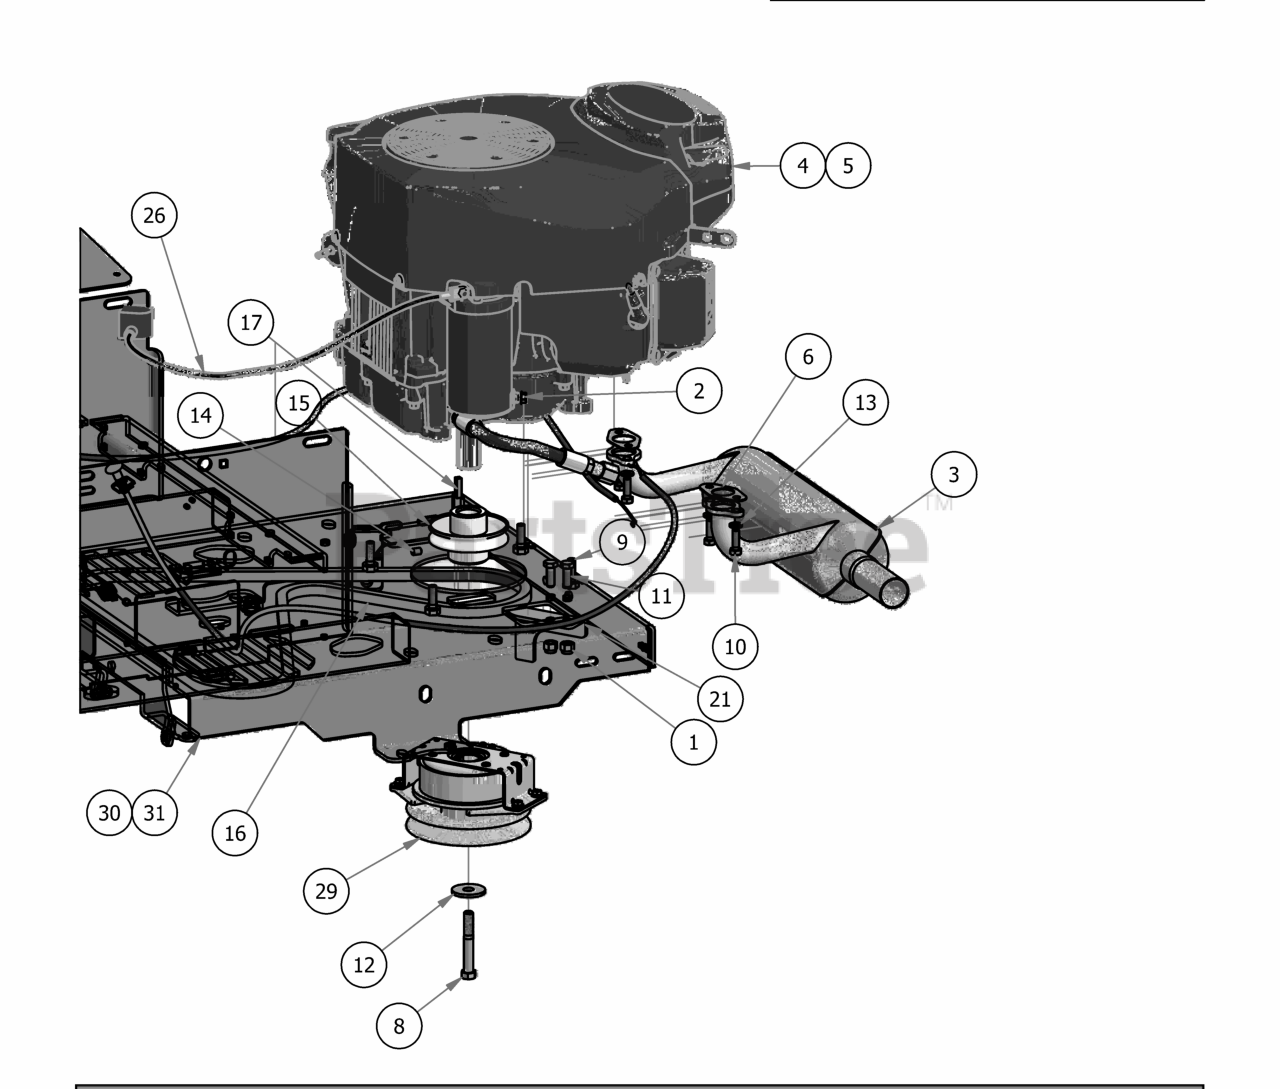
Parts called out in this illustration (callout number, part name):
1	3/8 Nylock Nut
2	1/4-20 Hex Flange Nuts Zinc w/Serrations
3	Kohler Muffler
4	Kohler MZ Magnum 740cc
5	Kohler KT-725
6	Exhaust Gasket
7	Spark Plug
8	7/16"-20 x 3" Hex Bolt Gr. 8
9	3/8 x 1 1/8 bolt
10	5/16" x 1" Bolt
11	3/8" x 1" Hex Bolt
12	1/2 Belleville Washer
13	5/16" Lock Washer
14	3/8" Set Screw
15	3-3/4" Motor Pulley
17	1/4" x 1" Key
18	37" Fuel Line Assembly
19	Oil drain Hose
21	2017 MZ Clutch Stop
22	KT-725 & KT-740 Precleaner
23	KT-725 & KT-740 Air Element
24	KT-725 & KT-740 Oil Filter
25	Universal Fuel Filter
26	Ground Cable
27	12" Red Battery Cable
28	MZ Kohler EPA Canister Assembly
30	2017 MZ/ZT 54"-62" Frame
31	2017 MZ/ZT 42"-48" Frame
32	2017 MZ Magnum Control Panel
33	2017 MZ Control Panel Assembly
